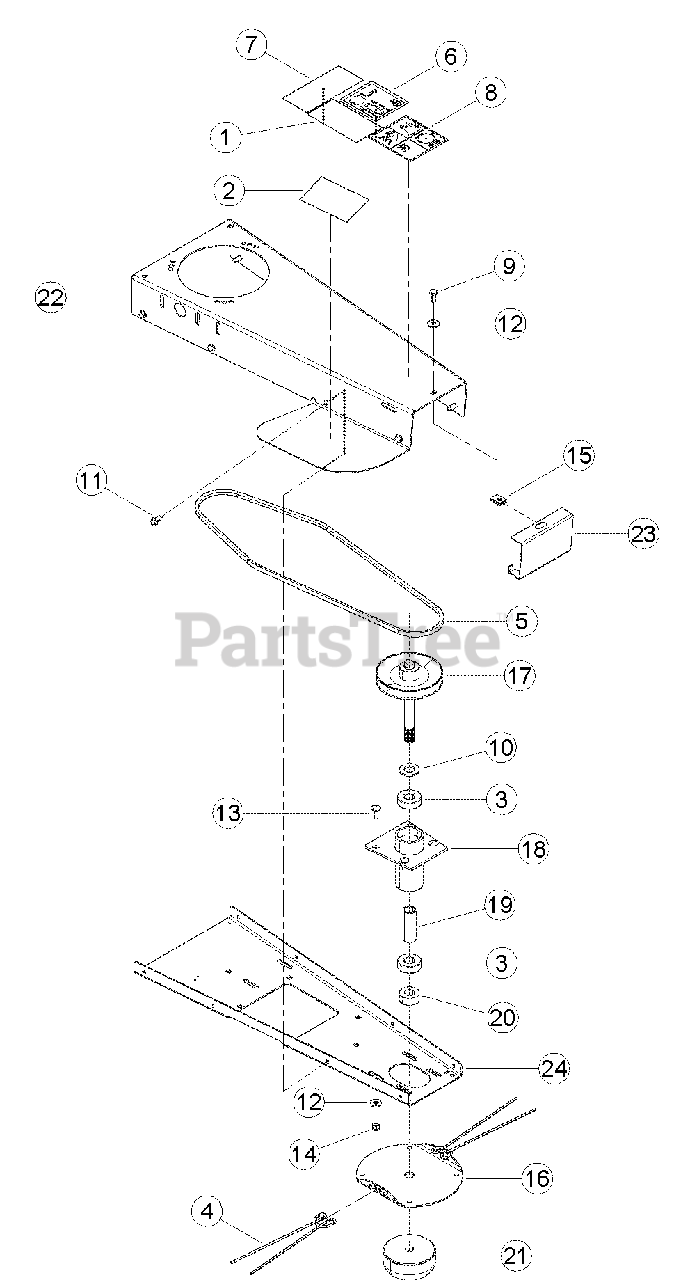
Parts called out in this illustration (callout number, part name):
1	DECAL, VAC DEBRIS
2	DECAL, GRINDER DANGER
3	BEARING, 3/4 BALL
4	STRING, .155 X 20-1/2
5	BELT, 3L X 52
6	DECAL, 98 DB
6	DECAL, 101 DB
7	DECAL, MULTILINGUAL MANUAL
8	DECAL, PROTECTION
9	BOLT, 5/16 3/4 HEX HD GR5 ZP
10	WASHER, 3/4 SAE FLAT ZP
11	SCREW, 11/32 X 7/8 HWH AB THREAD ZP
12	WASHER, 5/16 FLAT ZP
13	BOLT, 5/16 X 7/8 CRG GR5 NC ZP
14	NUT, 5/16 NE NYLOCK ZP
15	NUT 5/16-18 TINNERMAN U-TYPE
16	DISK, TRIMMER HEAD
17	WELDMENT, TRIMMER PULLEY
18	WELDMENT, SPINDLE HUB
19	SPACER, TRIMMER SPINDLE
20	SPACER, TRIMMER HEAD
21	WELDMENT, TRIMMER HEAD USE 72704-12
22	BODY, TRIMMER
23	COVER, FRONT TRIMMER
24	BOTTOM, TRIMMER FRAME
